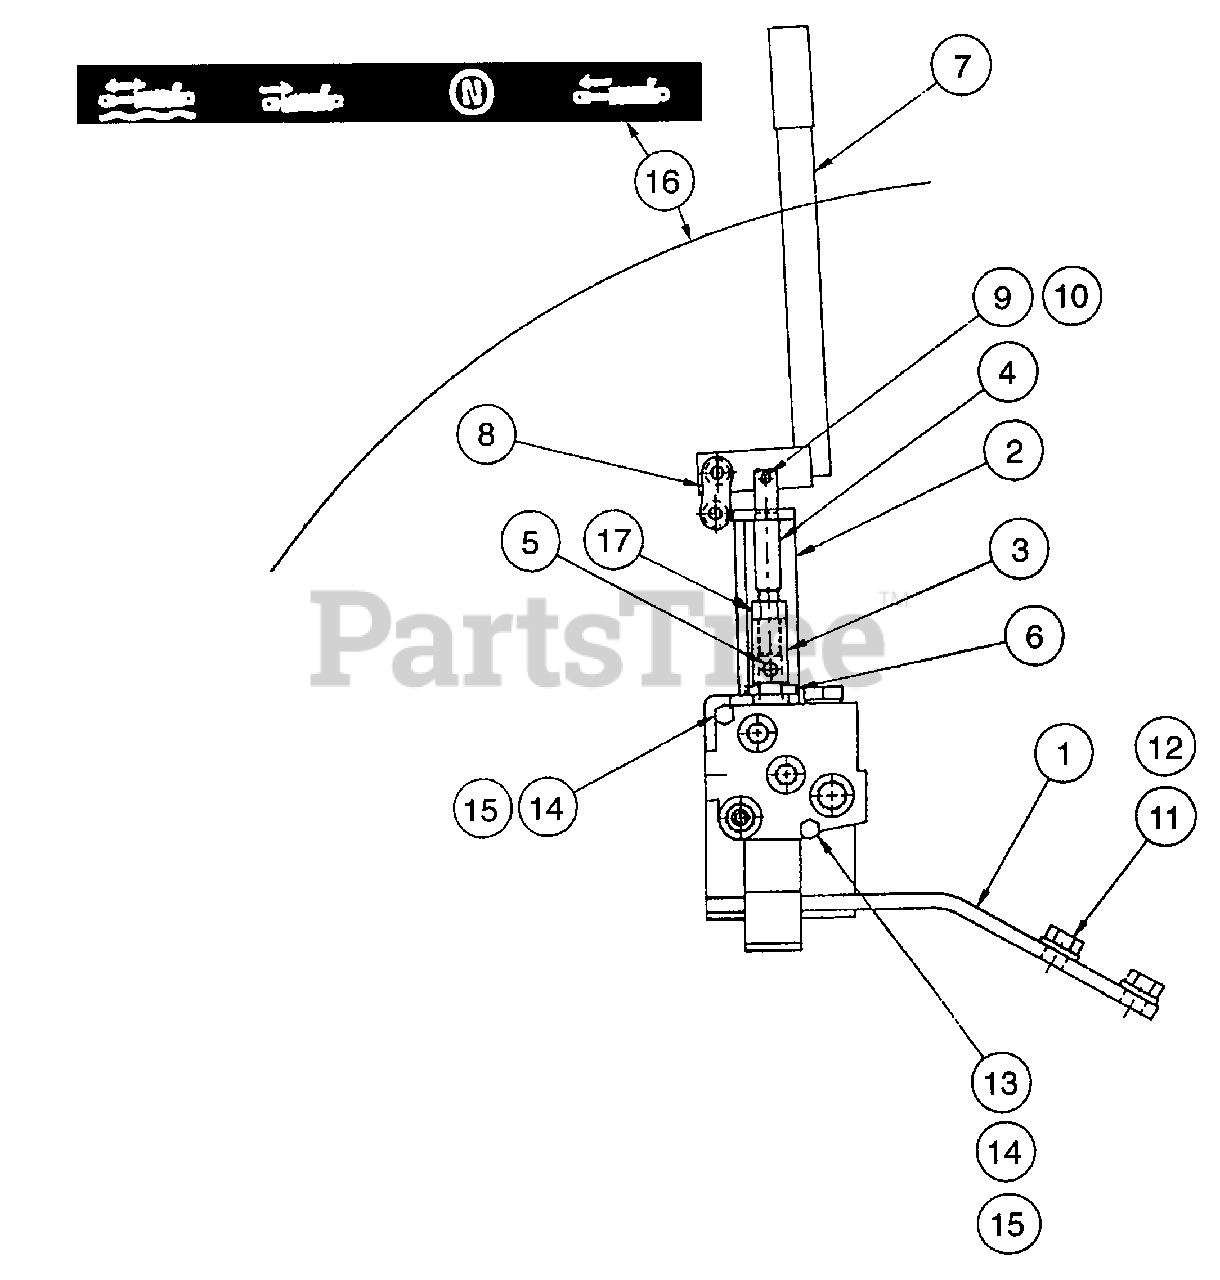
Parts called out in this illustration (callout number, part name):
1	Valve plate assembly
2	Stand assembly
5	Spring pin
6	Socket head cap screw M6-1 x 12mm
7	Handle assembly
8	Chain link assembly
9	Clevis pin
10	Cotter pin
11	Bolt M14-2 x 45mm
12	Lockwasher
13	Bolt 5/16 - 18 x 2-1/4
14	5/16 NC Nut
15	5/16 Lockwasher
16	Decal
17	5/8 NC Jam nut
